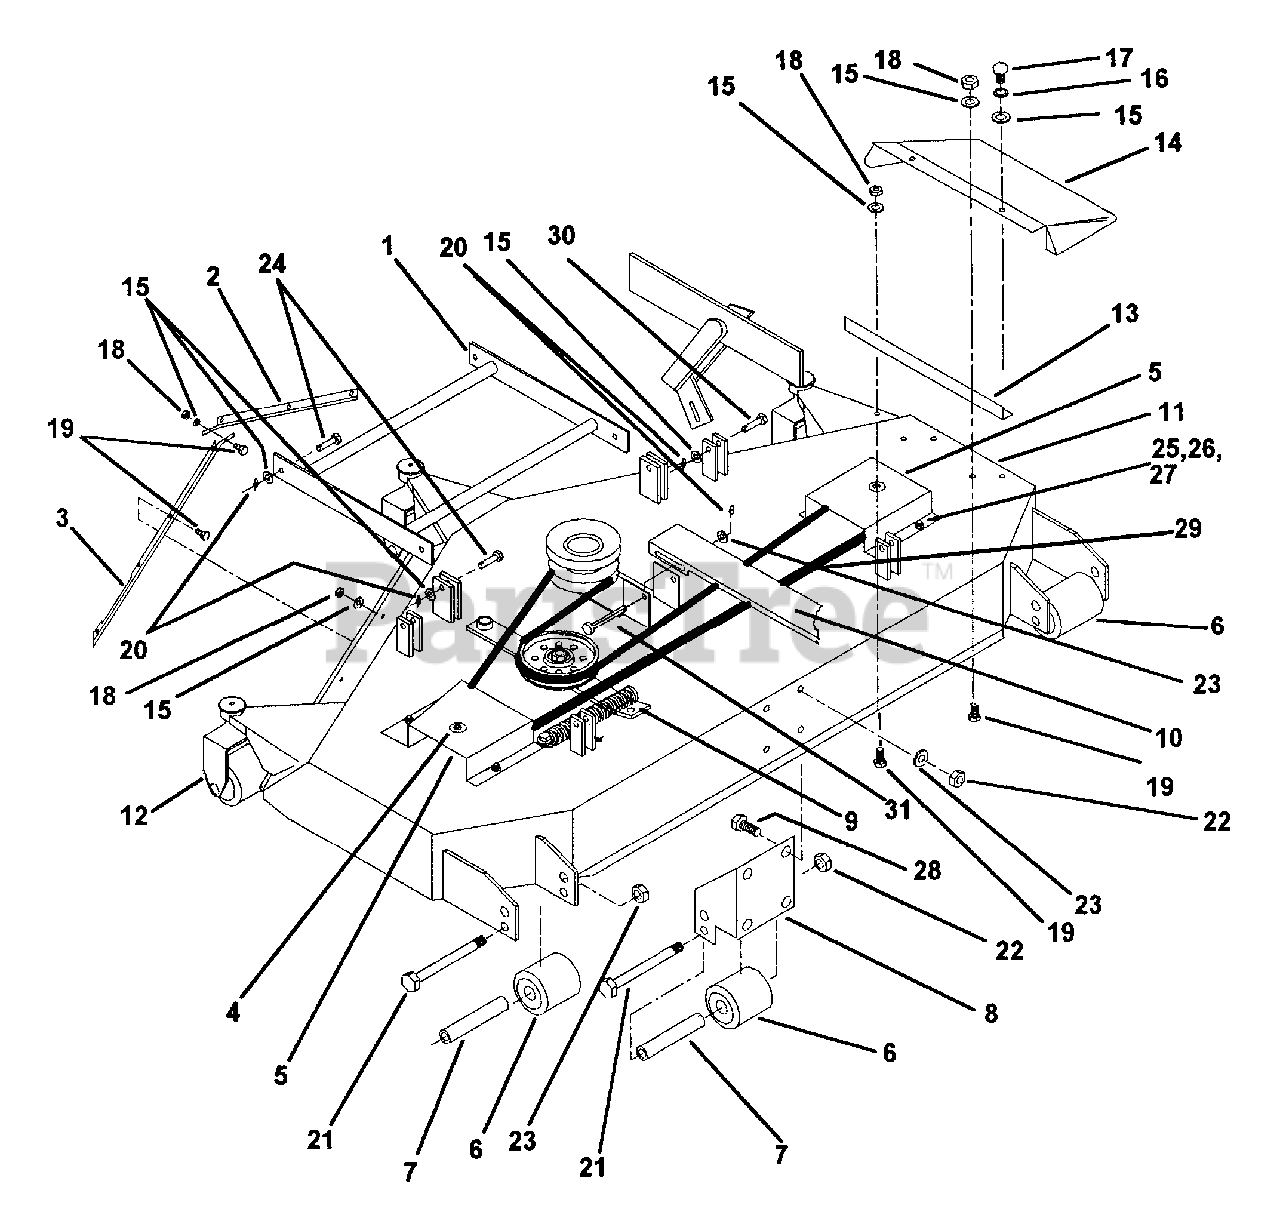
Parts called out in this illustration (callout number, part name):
1	DRAG BAR WELDMENT
2	LIP BAFFLE R.H.
3	LIP BAFFLE L.H.
4	SPINDLE ASSEMBLY
5	BELT GUARD
6	ROLLER, 3-3/4 X 4-13/16" LONG
7	BUSHING
8	BRACKET, REAR CENTER
9	SINGLE IDLER PARTS
10	DOUBLE IDLER CHANNEL ASSEMBLY
11	60" DECK WELDMENT
12	60" DECK CASTER WHEEL
13	OUTLET STIFFENER
14	CHUTE ASSEMBLY
15	WASHER, FLAT STD. 5/16"
16	LOCK WASHER, INT. STAR 5/16"
17	THUMBSCREW, 5/16-18 X 3/4" LONG
18	NUT, 5/16-18 NYLOC
19	BOLT, 5/16-18 X 3/4" CARRIAGE
20	COTTER RUE RING, 5/16 - 3/8 PIN
21	BOLT, 3/8-16 X 6" GR. 5
22	NUT, 3/8-16 NYLOC
23	WASHER, FLAT STD. 3/8"
24	CLEVIS PIN, 5/16 X 1-1/4" LONG
25	BOLT, 1/4-20 X 3/4" GR. 5
26	LOCK WASHER, 1/4" SPLIT SPRING
27	WASHER, FLAT STD. 1/4"
28	BOLT, 3/8-16 X 7/8" GR. 5
29	DECK CROSS BELT A-112, KEVLAR
30	CLEVIS PIN, 3/8 X 2" LONG
31	CLEVIS PIN, 3/8 X 2-3/4 O.A.L.
